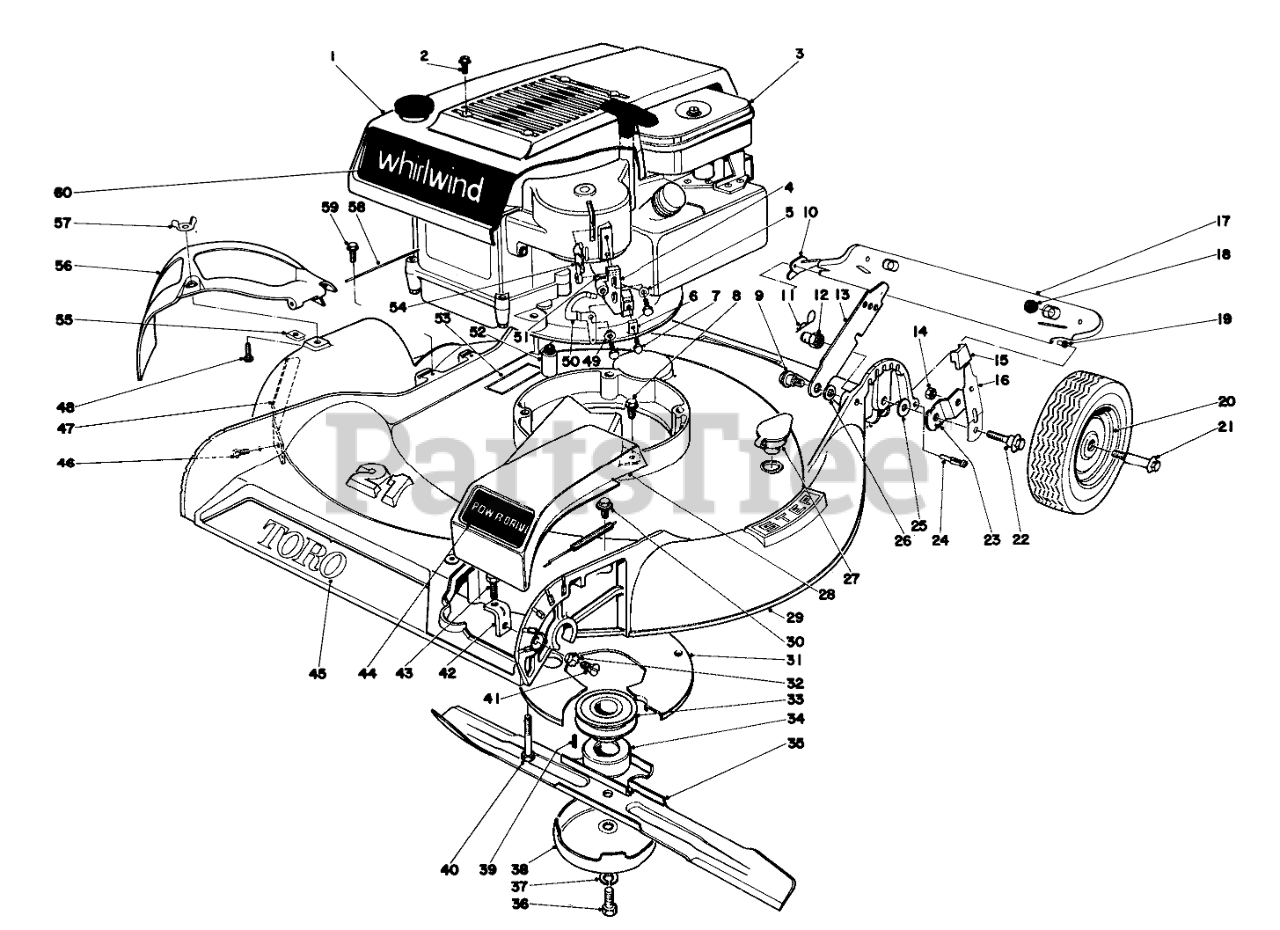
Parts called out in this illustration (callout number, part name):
1	Shroud
2	8X1/2 SELF TAP SCREW
3	Engine
4	Pivot Block (Incl. Ref. No. 51)
5	WASHER-FLAT
7	SCREW-SHWH
8	SCREW
9	SCREW-SHOULDER
10	Restraint R.H.
11	PIN-COTTER, HAIR
12	HANDLE PIVOT NUT
13	Latch
14	Nut
15	Arm Knob
16	Spring Arm
17	Rear Safety Shield (Incl. Ref. No.18& 19)
18	SKID BUTTON
19	SAFTEY SHIELD BUSHING
20	Wheel Assembly
22	PIVOT SCREW
23	PIVOT ARM PLATED
24	SAFTEY SHIELD SCREW
25	WASHER-PIVOT
26	SPACER
27	WASHOUT PLUG
28	Guard, Belt
29	Housing
30	SCREW-HWHTF
31	Grass Guard
32	Lockwasher
33	Pulley
34	Blade Retailer
35	Blade
36	SPECIAL SCREW
37	WASHER-LOCK
38	Anti Scalp Cup
39	Key Square
40	3/8-16 X 2-3/4 CAPSCR
42	ADJ BRACKET
43	SCREW-HH
44	Decal Power Drive
45	Decal Toro
46	SCREW-HWH
47	Bar Safety
49	BUSHING
50	Cam-Interlock
51	PIN-ROLL, SLOT
52	Extension Oil Drain
53	Decal
54	INTERLOCK LEVER
56	Deflector
57	NUT-WING SPECL
58	HINGE PIN
59	SCREW
60	Decal Whirlwind
